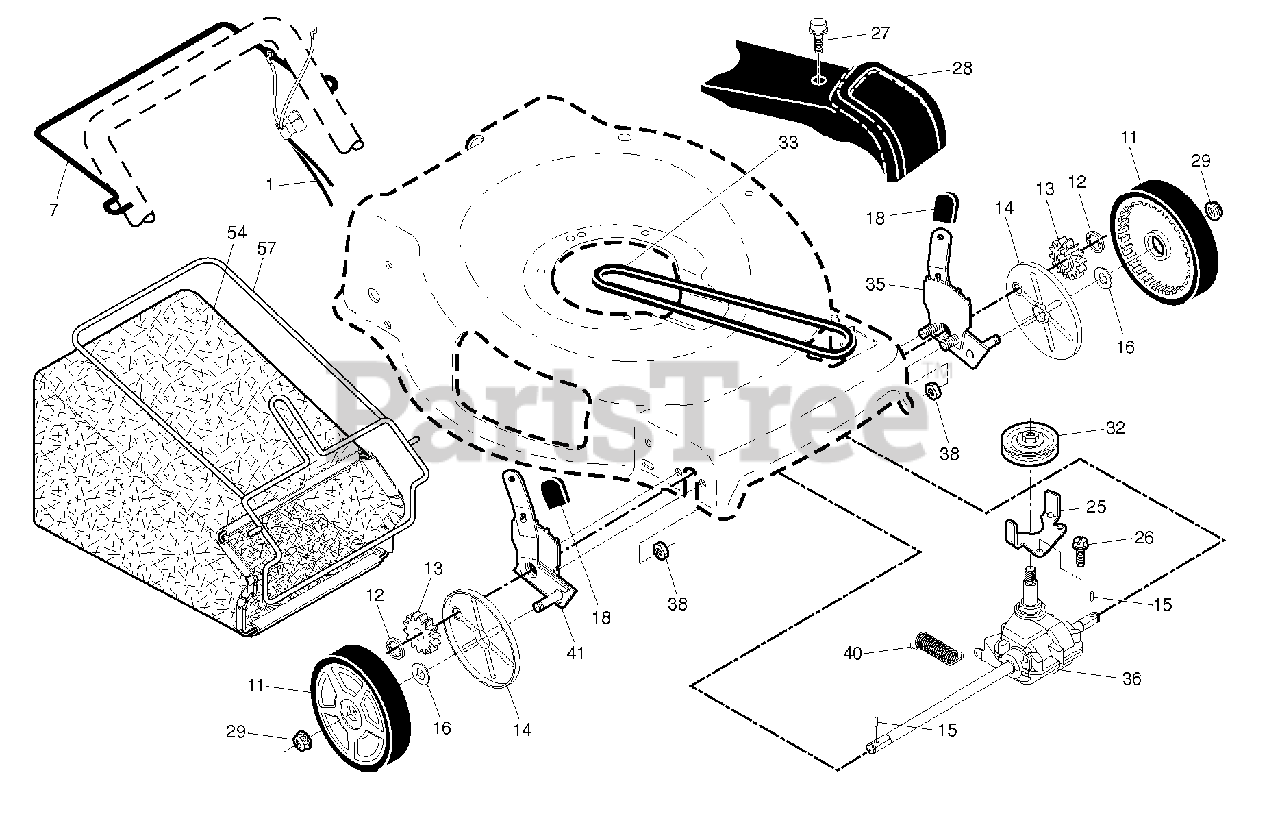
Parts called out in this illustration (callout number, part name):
1	Drive Cable, S/S 22+ Fwgd
7	BAIL.DRIVE.S/S.ROUND.MARI.21
11	WHEEL.8X1.75.5SPK.RAD3.BLACK
12	E-RING 7/16 RE
13	PINION.14.TEETH.FGD
14	COVER.DUST.WHEEL.INNER.WALK
15	PAWL, DRIVE
16	WASHER FLUT
18	SELECTOR KNOB
25	BRACKET.BELT.GUIDE.22+FGD.BZP
27	SCREW, HEX HD TAPPING #10-24 1
28	Drive Cover Assembly, 419930 Ce
29	NUT.HEX.FLANGE.3/8-16.LOCKNUT
32	PULLEY.DRIVEN.EZ/VARI (2 2MC)
33	BELT.DRIVE.FGD.
35	Adjuster Assembly Kit, LH Front
36	TRANSMISSION.22+.FWGD.SS
38	NUT.FLANGE.1-4-20-SERR
41	Adjuster Assembly Kit, RH Front
54	GBAG.A1640416S.BLK.PPRO.MRG.
57	Grass Bag Frame, 22+ Black
